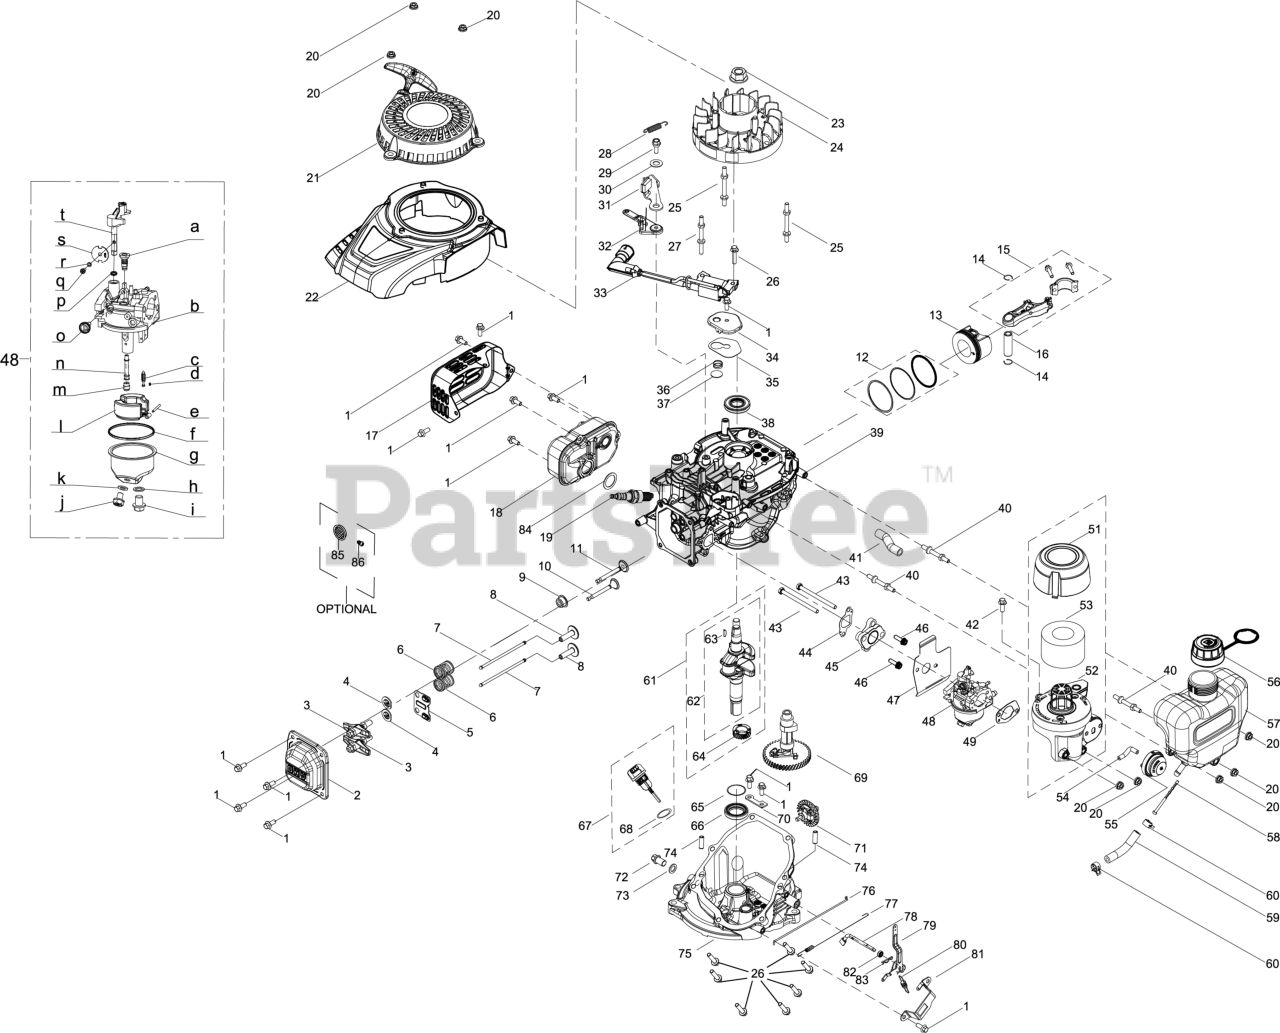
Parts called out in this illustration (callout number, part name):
1	BOLT M6-1 x 14 GR8.8
2	VALVE COVER
3	ROCKER ARM ASSEMBLY
4	VALVE SPRING RETAINER
5	PUSH ROD GUIDE
6	VALVE SPRING
7	PUSH ROD GUIDE
8	TAPPET (LIFTER)
9	INTAKE VALVE SEAL
10	EXHAUST VALVE
11	INTAKE VALVE
12	PISTON RING SET
14	SNAP RING-PISTON PIN
15	CONNECTING ROD ASSEMBLY
16	PISTON PIN
17	MUFFLER GUARD
19	SPARK PLUG
21	STARTER RECOIL ASSEMBLY
22	SHROUD ASSEMBLY
23	FLYWHEEL NUT
24	FLYWHEEL
25	STUD M6 x 75
26	BOLT M6-1 x 25 GR8.8
27	STUD M6 x 73
28	ENGINE BRAKE SPRING
29	ENGINE BRAKE PIN M6-1.0 MM
30	FLAT WASHER 10x20x1.0 MM
31	ENGINE BRAKE ARM
32	ENGINE BRAKE LOWER BRACKET
33	IGNITION COIL
34	BREATHER COVER PLATE
35	BREATHER GASKET
36	BREATHER VALVE SPRING
37	BREATHER VALVE
38	UPPER CRANKSHAFT SEAL
40	FUEL TANK MOUNTING STUD M6X59.5
41	BREATHER HOSE
42	BOLT M6 x 16
43	BOLT M6X80
44	CARBURETOR INSULATION GASKET
45	CARBURETOR INSULATOR
46	BOLT M6X20
47	CARBURETOR GASKET
48	CARBURETOR
49	AIR FILTER BASE GASKET
51	AIR FILTER COVER
52	AIR FILTER BASE
53	AIR FILTER - FOAM
54	PRIMER HOSE
55	VENTED PRIMER ASSEMBLY
56	FUEL CAP W/TETHER
58	FUEL FILTER
59	FUEL HOSE
60	CARBURETOR HOSE CLAMP
61	CRANKSHAFT ASSEMBLY
62	CRANKSHAFT ASSEMBLY
63	WOODRUFF KEY
65	THRUST WASHER
66	LOWER CRANKSHAFT SEAL
67	DIPSTICK ASSEMBLY
68	DIPSTICK SEAL
69	CAMSHAFT ASSEMBLY
70	GOVERNOR GEAR MOUNTING PLATE
71	GEAR GOVERNOR
72	OIL DRAIN PLUG
73	WASHER
74	DOWEL PIN 7X20
75	CRANKCASE COVER
76	THROTTLE LINKAGE
77	THROTTLE LINKAGE SPRING
78	GOVERNOR ARM SHAFT
79	GOVERNOR ARM ASSEMBLY
80	GOVERNOR SPRING
81	COMPONENT BRACKET
82	GOVERNOR SEAL
83	COTTER PIN
84	MUFFLER GASKET
85	SPARK ARRESTOR
86	SCREW M3.5 x 9.5
